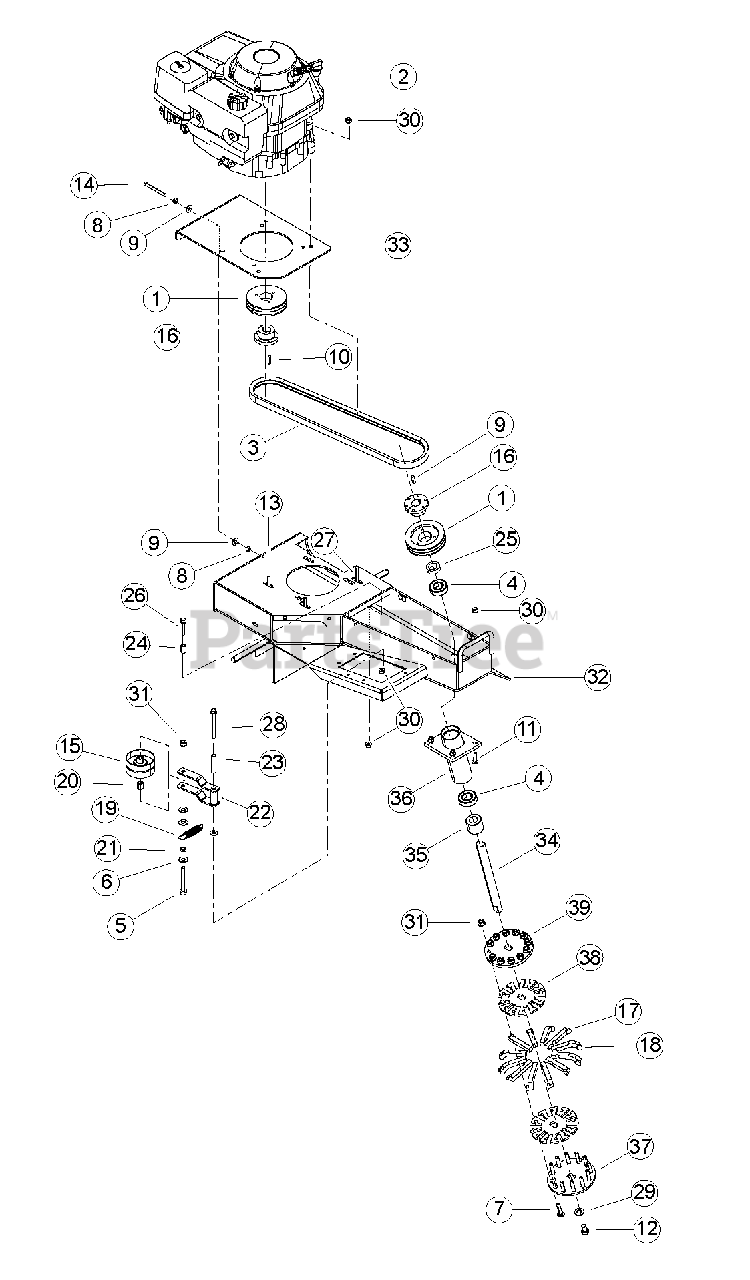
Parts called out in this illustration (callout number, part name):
1	SHEAVE, 3V4.5-2 GROOVE SH
2	ENGINE, 11 HP HONDA GXV
3	BELT, 3VX530 DOUBLE BANDED
4	BEARING, 1 INCH BALL
5	BOLT, 3/8 X 3 GR5 HEX CAPSCREW ZP
6	WASHER, 3/8 FLAT ZP (67PCS/LB)
7	BOLT, 3/8 X 1 3/4 GR5 CARR BLT ZP
8	NUT, 5/16 HEX NC - ZP
9	WASHER, 5/16 FLAT ZP
10	KEY, 1/4 SQ X 1" LG
11	BOLT, 5/16 X 1-1/4 GR5 ZP CRG
12	BOLT, 1/2-20 X 3/4 GR5 HHCS NF ZP
13	BOLT, 5/16 X 1-1/4 HCS NF GR5 ZP
14	SCREW, 5/16 X 3 SQ HD SET
15	PULLEY, 3-1/4 FLAT IDLER
16	BUSHING, SH 1 INCH
17	STUMP CUTTER TEETH, STRAIGHT
18	STUMP CUTTER TEETH, R.H.
19	SPRING, 3/4 OD EXTENSION
20	3/4 LONG IDLER SPACER TUBE
21	SPACER IDLER PIVOT
22	WELDMENT, 2 BELT IDLER
23	PIVOT TUBE
24	SPACER, .54 X .88
25	SPACER, 1-1/2 X 1/2
26	BOLT, 5/16 X 1-3/4 FLANGE NC
27	BOLT, 5/16 X 2-1/4 FLANGE NC
28	BOLT, 5/16 X 3-1/2 SERR FLANGE NC
29	WASHER, 1/2 HI-STRENGTH SAE ZP
30	NUT, 5/16-18 NYLOCK-FLANGE
31	NUT, 3/8-16 NYLOCK FLANGE
32	WELDMENT, STUMPGRINDER FRAME
33	PLATE, ENGINE SLIDE
34	SPINDLE, CUTTER SG 12 BLADE
35	TUBE, SPACER 1-3/4 X 1.520
36	WELDMENT, SPINDLE HUB
37	PLATE, COVER STUMPGRINDER HEAD
38	PLATE, SPACER STUMPGRINDER HEAD
39	PLATE, DISK STUMPGRINDER HEAD
